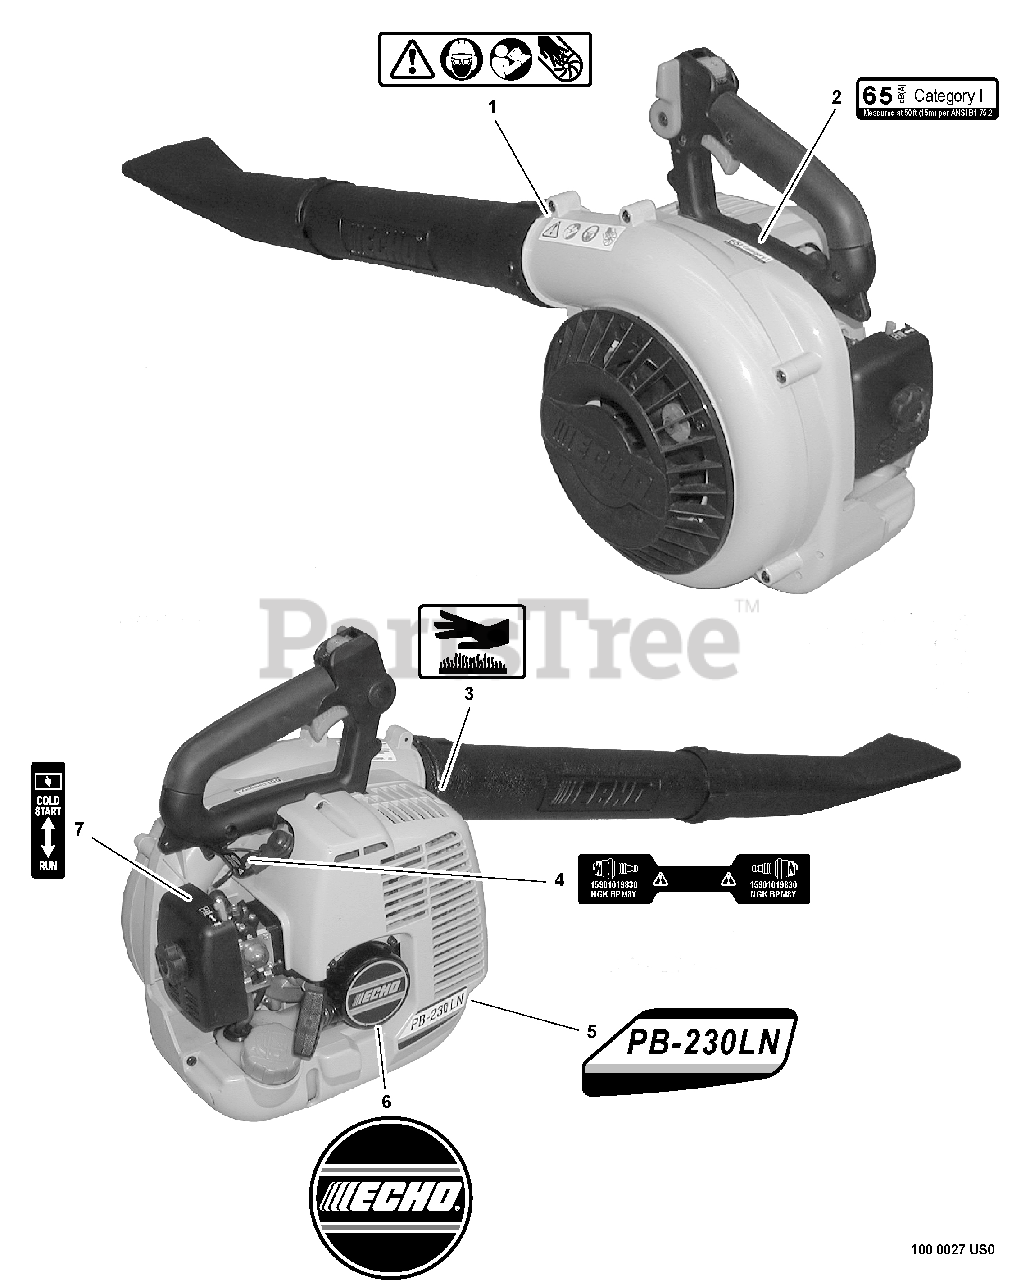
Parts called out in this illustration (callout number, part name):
1	LABEL - CAUTION
2	LABEL - NOISE 65dB(A) CAT I
3	LABEL - HOT SURFACE
4	LABEL - SPARK PLUG -- BPM-8Y
5	LABEL - MODEL PB-230LN
6	LABEL - ECHO
7	LABEL - CHOKE
